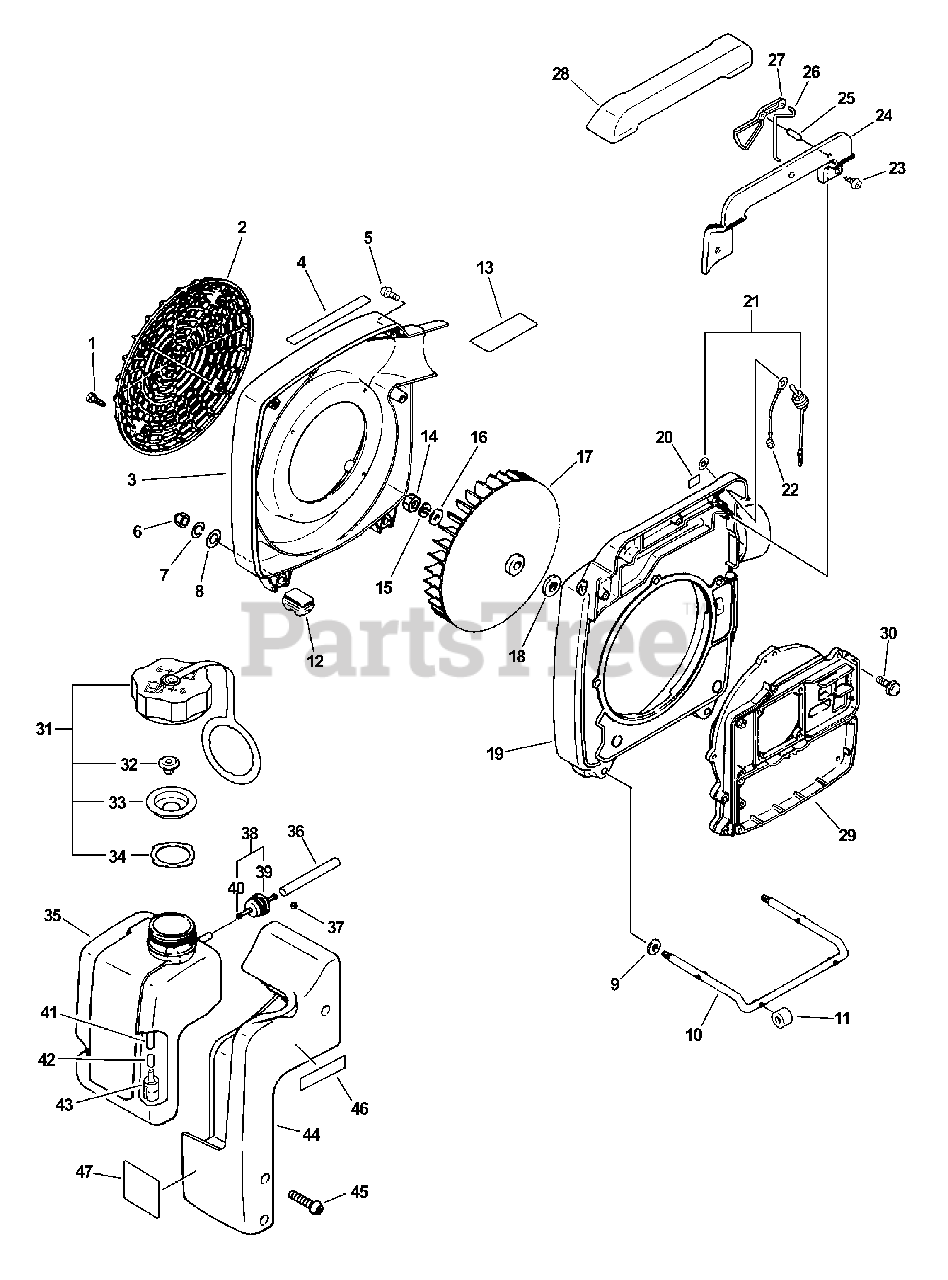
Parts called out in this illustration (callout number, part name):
1	SCREW - 5X20
2	GUARD, DEBRIS
3	COVER, FAN - LEFT
4	LABEL - MODEL PB-210
4	LABEL - MODEL PB-211
5	SCREW - 5X25
6	NUT - 6 -- CAP
7	LOCKWASHER - 6
8	WASHER - 6
13	LABEL - NOISE 65dB(A) CAT I
15	LOCKWASHER - 8
16	WASHER - 8
18	WASHER - 10
19	COVER, FAN - LEFT
20	LABEL - STOP
21	IGNITION SWITCH ASSY
22	LEAD - GROUND
23	SCREW - 4X16
24	COVER, HANDLE
25	PIN - SPRING -- 5X18
26	ROD, THROTTLE
27	TRIGGER, THROTTLE
28	GRIP, HANDLE
29	BRACKET, ENGINE
30	SCREW - 5X18
31	CAP ASSY
33	HOLDER, VENT
34	GASKET, CAP
35	TANK, FUEL
36	PIPE, FUEL - 3X7X65
37	CLIP - 6.5
38	GROMMET KIT
40	CONNECTOR, PIPE
41	PIPE - 3X7X135 -- BLACK
43	FILTER, FUEL
44	BRACKET, FUEL TANK
45	SCREW - 4X25
46	LABEL - ECHO
47	LABEL - CAUTION
